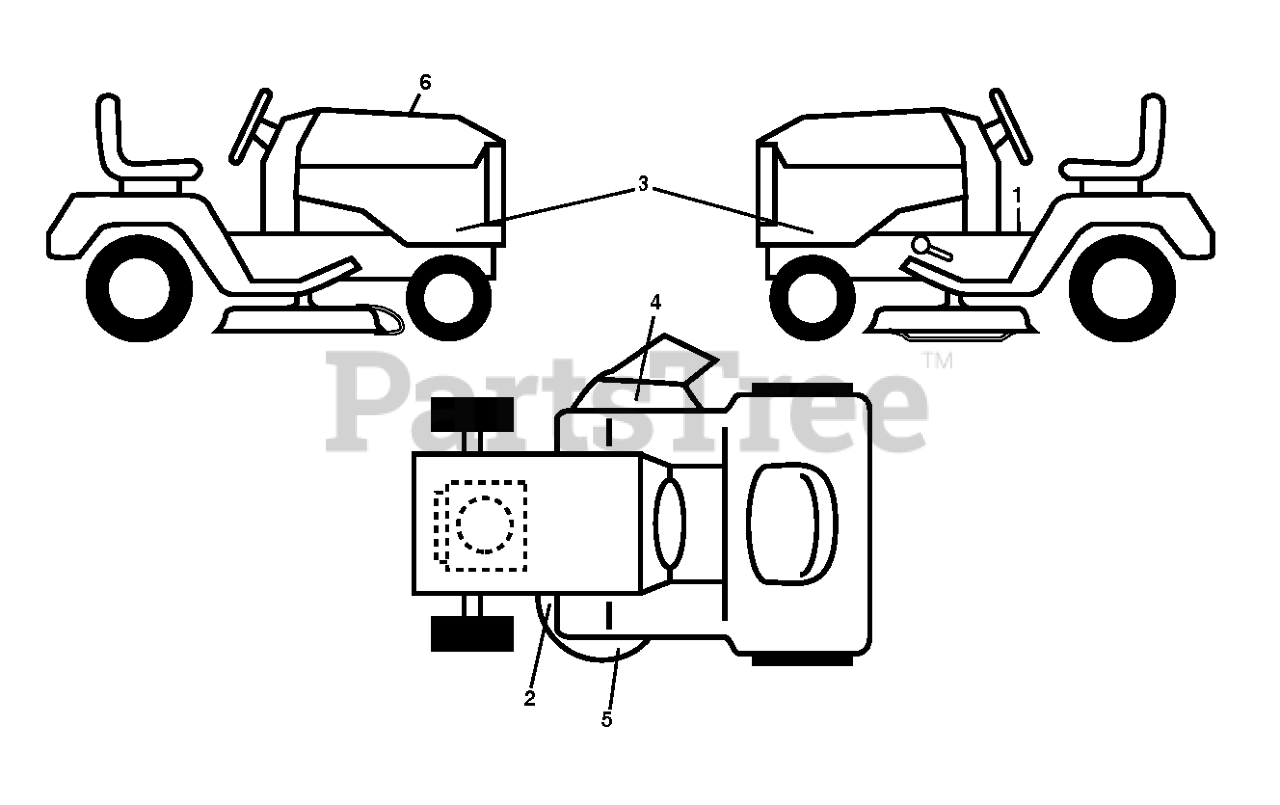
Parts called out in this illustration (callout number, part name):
1	DECAL.WARNING.2007.ENG/FR
2	DECAL.DECK.BELT.ROUTE.42"2021
2	DECAL.V-BELT.SCH.42/46"MEC/ELE
4	DECAL.DECK.DEFLECTOR.WARNING
4	DECAL, DECK DEFLECTOR, WARNING
5	DECAL.DECK.STAMP.BIOCLIPCMP.HU
